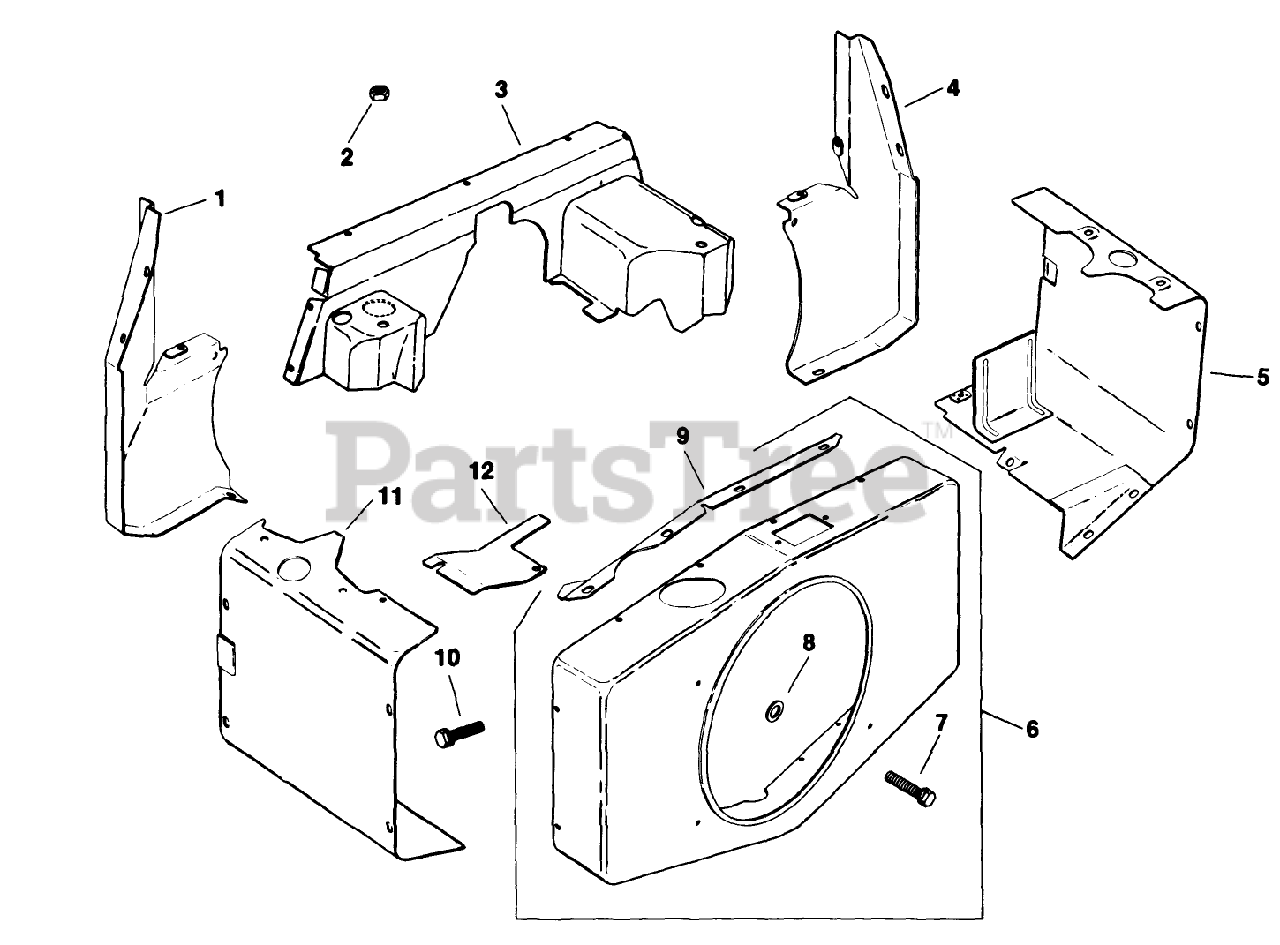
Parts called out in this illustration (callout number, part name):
1	Duct-#1 Side Air
2	Nut
3	Cover-Air Duct
4	Duct-#2 Side Air
5	Baffle-#1 Cylinder Head
6	Kit-Blower Housing (Incl. Ref. #7, 8 & 12)
7	Screw-H.C
9	Screw
10	Baffle-Cylinder Head
11	Baffle-Cylinder Head
12	Support-Upper Housing
